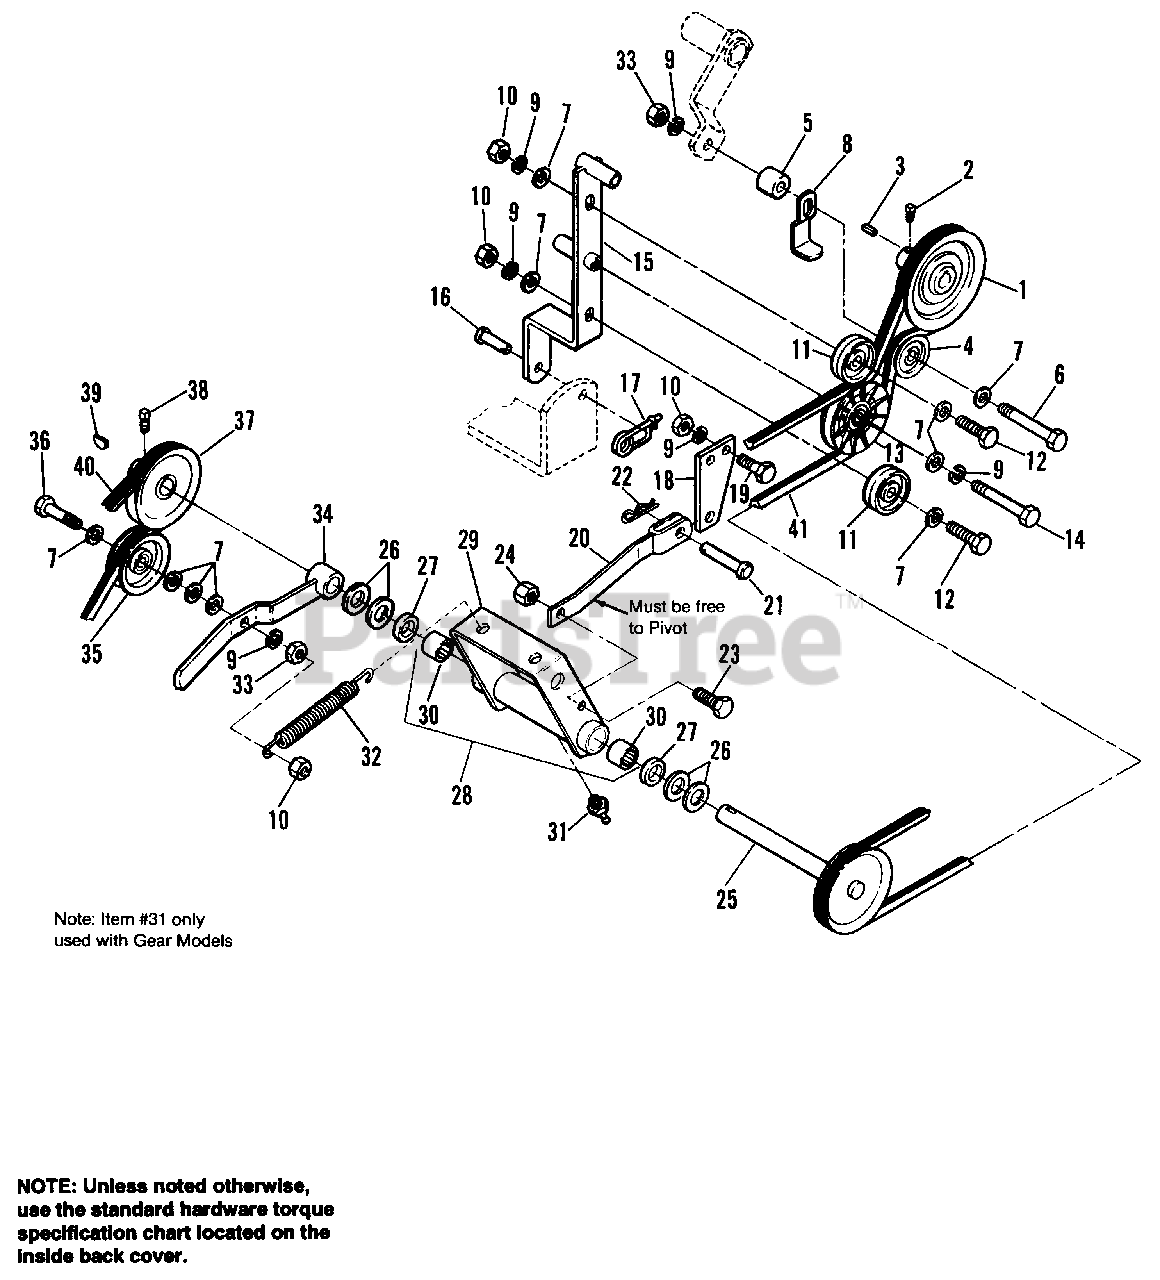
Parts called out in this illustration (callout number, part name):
2	SETSCREW, 3/8-16 x 1/2
4	PULLEY ASSY. (Incl. Ref. No. 5)
6	CAPSCREW, Hex, 3/8-16 x 2-3/4
7	WASHER, Plain, 3/8
8	GUARD, Spring
9	LOCKWASHER, 3/8
10	NUT, Hex, Full, 3/8-16
11	PULLEY, Idler
12	CAPSCREW, Hex, 3/8-16 x 1-3/4
13	PULLEY, Idler
14	CAPSCREW, Hex, 3/8-16 x 1-1/4
15	ARM ASSY., Idler
17	CLIP, Safety
18	ANCHOR, Jackshaft (Used on Gear Models only)
19	CAPSCREW, Hex, 3/8-16 x 1
20	ANCHOR ASSY.
21	PIN
23	CAPSCREW, Hex, 5/16-18 x 1
24	NUT, Hex, Centerlock, 5/16-18
25	PULLEY ASSY., Jackshaft
26	WASHER, 3/4
28	CLEVIS ASSY., w/Bearings (Incl. Ref. Nos. 29 & 30)
30	BEARING, Needle
31	FITTING, Grease
32	SPRING, Extension
33	NUT, Hex, Jam Lock, 3/8-16
34	ARM ASSY., Idler
35	PULLEY, Idler
36	CAPSCREW, Hex, 3/8-16 x 2
37	PULLEY ASSY.
38	SETSCREW, 5/16-18
39	KEY, Woodruff #61
40	BELT, Primary
41	V-BELT, Drive
